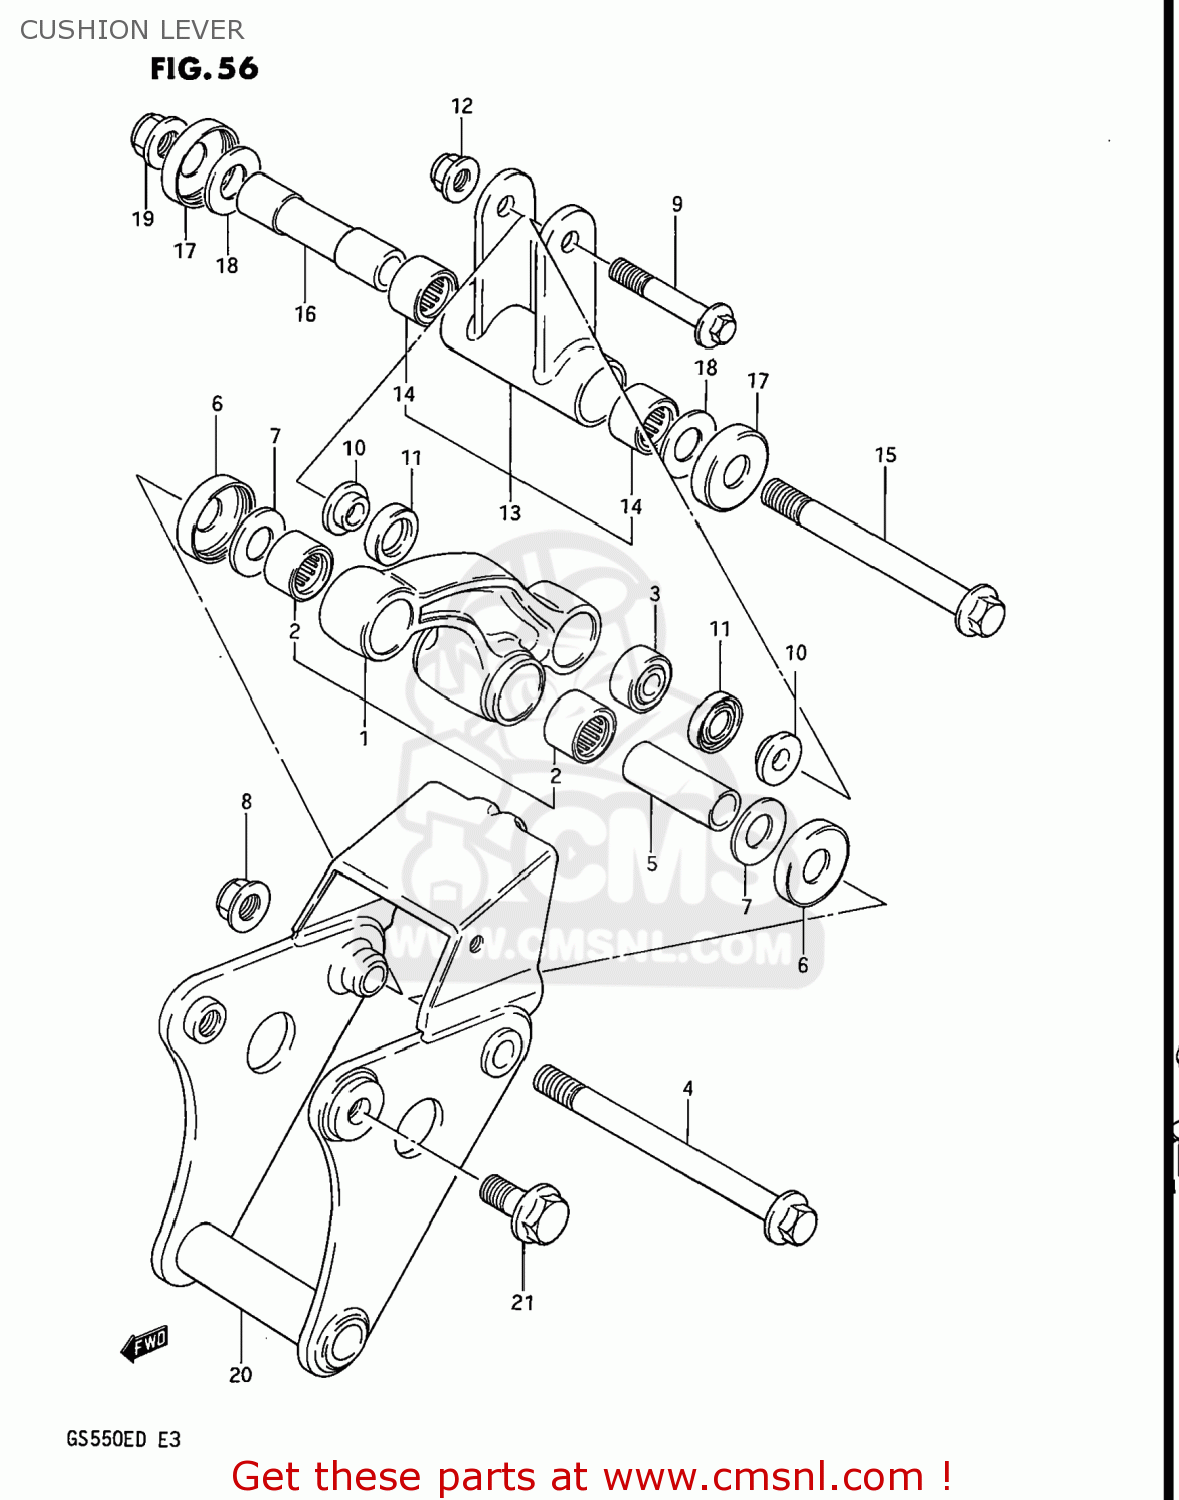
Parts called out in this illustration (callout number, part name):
1	LEVER SET,REAR CUSHION
2	ROLLER BEARING (17X24X2
3	BEARING(10X24X15)
4	SHAFT,REAR CUSHION LEVER
5	SPACER,REAR CUSHION LEVER
6	COVER,RR SWGARM DUST SEAL
7	WASHER
8	NUT 12MM
9	BOLT(10X52)
10	SPACER
11	DUST SEAL,RR CUSHION LEVER RR
12	NUT
13	LEVER SET,REAR CUSHION
14	ROLLER BEARING (17X24X2
15	BOLT,REAR CUSHION ROD
16	SPACER,REAR CUSHION ROD
17	COVER,RR SWGARM DUST SEAL
18	WASHER
19	NUT 12MM
20	HOLDER
21	BOLT(12X23)
